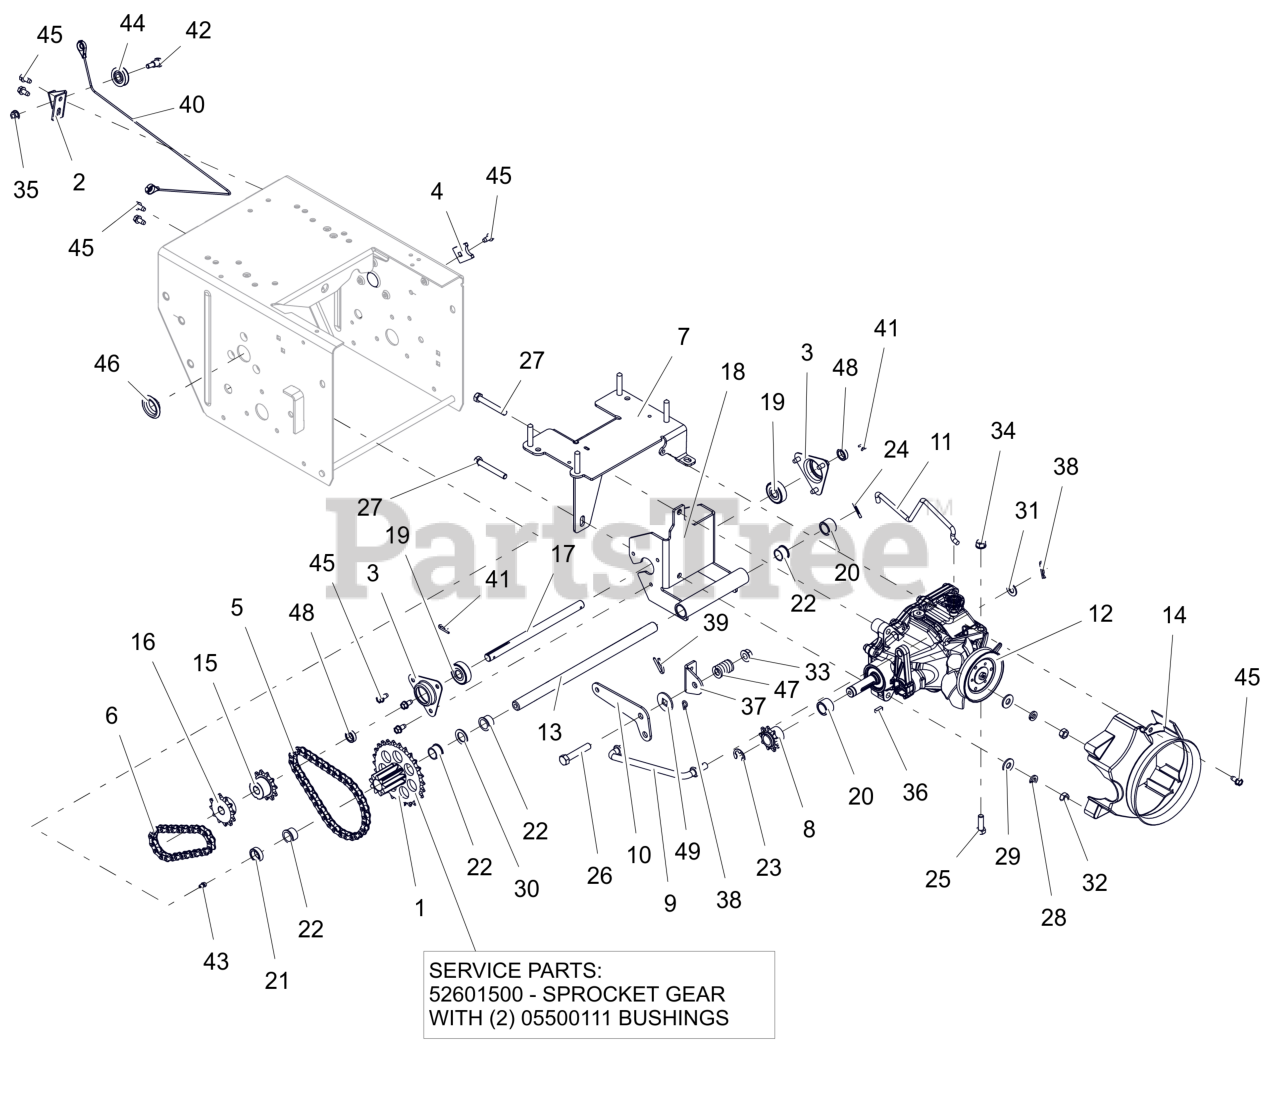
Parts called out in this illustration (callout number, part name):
1	PINION & SPROCKET
1	PINION & SPROCKET W/BUSHINGS
2	BRKT, CABLE PULLEY
3	FLANGE, BEARING
4	TAB, ANTI ROTATION
5	ROLLER CHAIN #41 - 34 PITCHES
6	CHAIN-ROLLER #41X26 PITCHES
7	BRACKET, HYDROSTATIC TRANS XLG
8	SPROCKET, PINION 9T W/KEY
9	ROD, HYDRO TRANS SHIFT
10	PIVOT, HYDRO TRANS SHIFT
11	ROD, HYDRO BYPASS
12	TRANSMISSION, HYDROSTATIC
13	SHAFT, PINION - HARDENED
14	SHROUD, HYDROGEAR RT-310
15	SPROCKET, 11 TOOTH
16	SPROCKET, 12 TOOTH
17	SHAFT, REDUCTION HEAT TREATED
18	SUPPORT, REDUCTION-BWT
19	BRG-BALL .500X1.38X.437
20	SPACER, .635X.880X.611
21	BSHG-SLV, .635X.880X.305
22	BSHG-FLG .625X.750X.500X.875
23	RG-RTNG-EXT .625X.042
24	@PIN-GRV .125X1.00 TP E ALLOY
25	BLT,HEX .31-18X1.00 G5 ZCC
26	BLT,HEX .38-16X2.00 G5 ZCC
27	BLT, HEX .31-18X2.25 G5 ZCC
28	WSHR, LK-HVY .312X.097 ZCC
29	WSHR,FLT .375X.875X.083 ZCC
30	WSHR, FLT .630X1.005X.062 ZCC
31	WSHR,FLT .406X.812X.065 ZCC
32	NUT, HEX .312-18 ZCC
33	NUT-LK-TOP-FLG .38-16 ZC120
34	NUT-LK-TOP-FLG .312-18 GF ZCC
35	NUT-LK-TOP-FLG .250-20 GF ZCC
36	KEY-SQ .187 X .50 X .187
37	BRACKET, HYDRO SHIFT PIVOT
38	PIN, HAIR #213 .08X1.19 ZCC
39	PIN, SPRING CLIP
40	CABLE, TRACTION, HYDRO PRO
41	CLIP, SPRING
42	BOLT, SHLDR -.375 X .375 X .25-20
43	ZERK,FITTING .25X.125 DRIVE IN
44	PULLEY, CABLE
45	SCR-TAP .25-20X.50 HWH ZCC
46	PLUG, HOLE - 1.125"
47	SG-COMP .187X.56X1.62
48	SPCR, SLV
49	FRICTION WASHER
